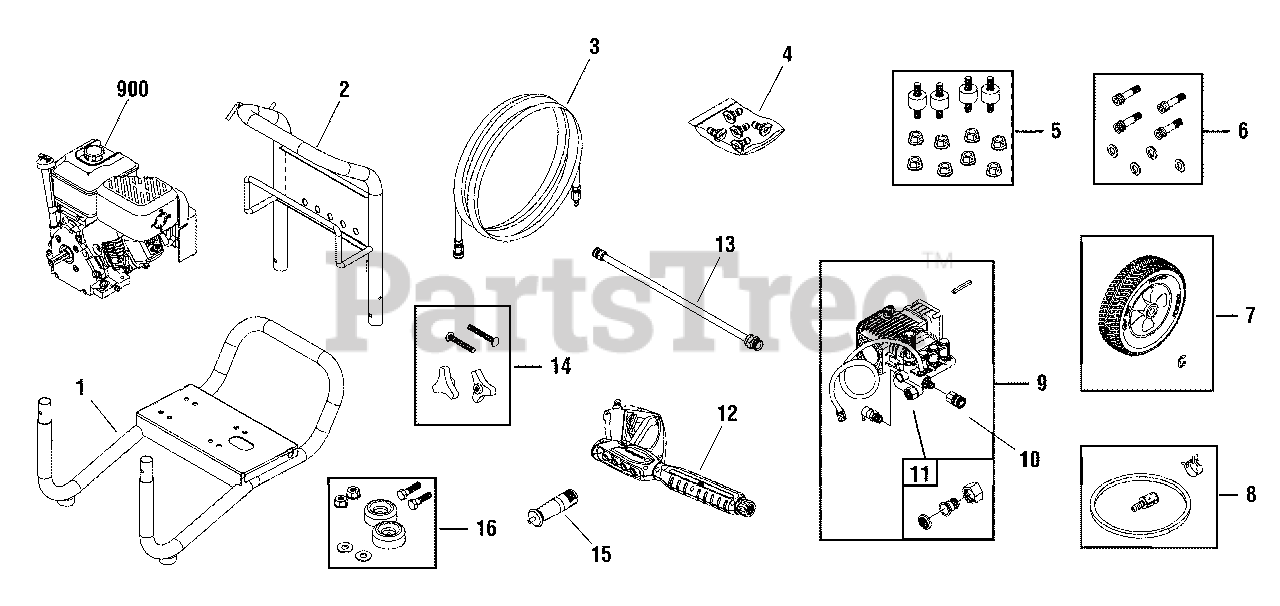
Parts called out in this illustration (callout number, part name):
4	KIT, QC Nozzles
5	KIT, Vibration Mount
6	KIT, Hardware, Pump Mounting
10	FITTING
11	ADAPTER, Garden Hose
13	EXTENSION, QC
14	KIT, Hardware, Handle
16	MOUNT, Vibration
900	* ENGINE
